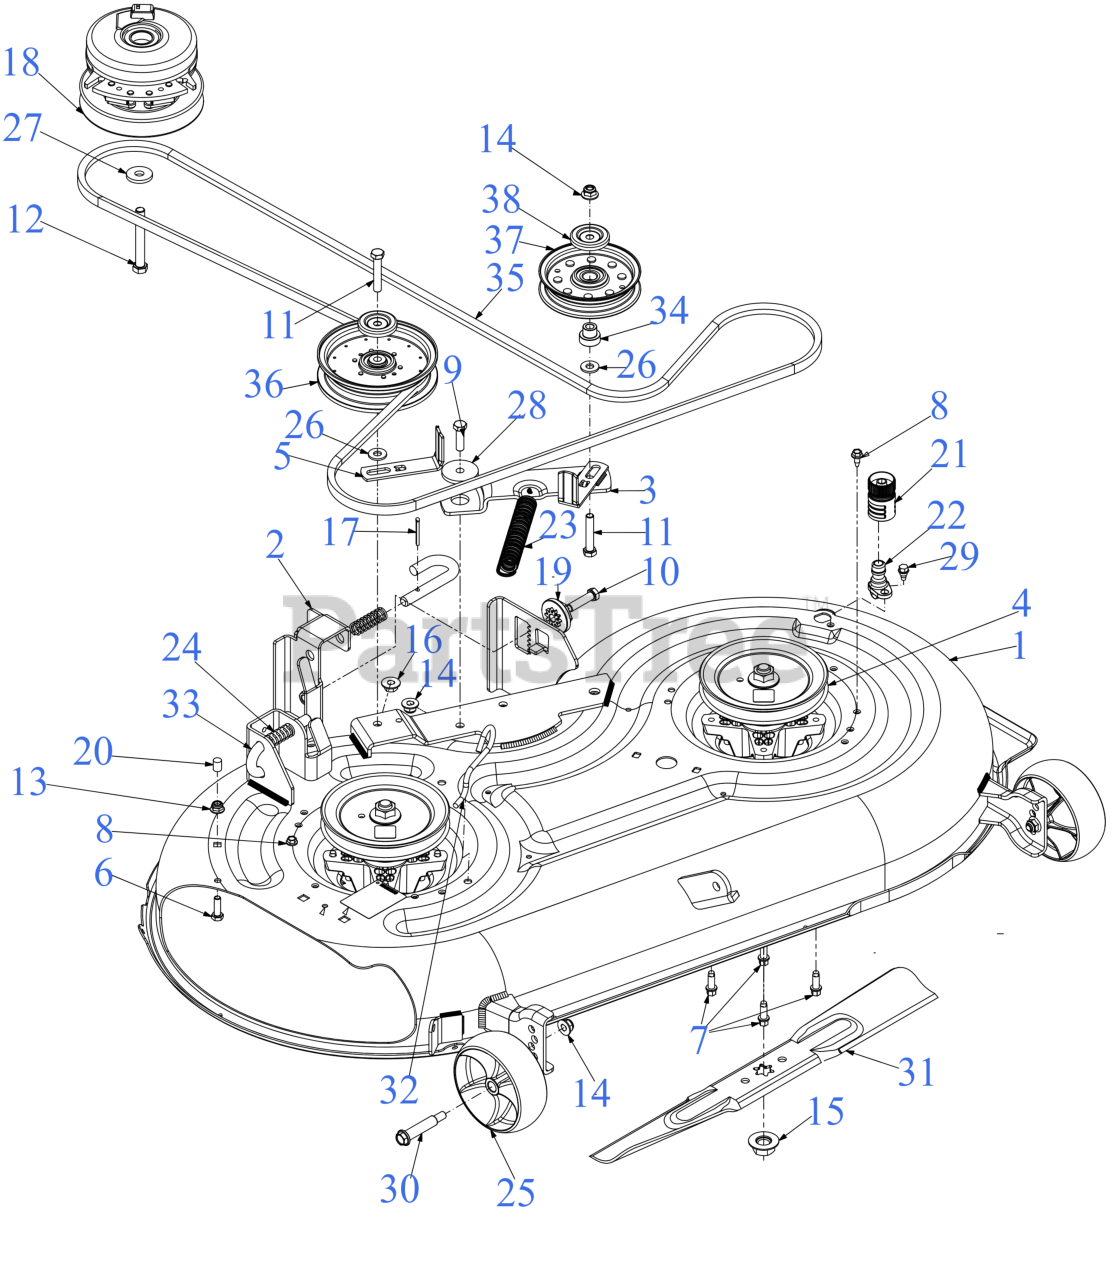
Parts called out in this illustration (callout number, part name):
3	42" IDLER PIVOT BRACKET
4	SPINDLE ASSEMBLY
4	Cub Cadet SPINDLE ASSEMBLY
6	SCREW 5/16-18 x 1.0 GR5
7	SCREW 5/16-18 x .875
8	SCREW 1/4-20X.625
9	SCREW 3/8-16 x 1.25 GR5
10	SCREW 3/8-16X1.5 GR5
11	SCREW 3/8-16 x 2.0 GR5
12	SCREW 7/16-20 x 3.25 GR5
13	FLANGE LOCK NUT 5/16-18
16	FLANGE LOCK NUT
17	COTTER PIN-5/32 DIA
18	ELECTRIC PTO CLUTCH
19	DECK ADJUSTMENT GEAR
21	WATER NOZZLE ADAPTER
22	DECK WASH NOZZLE
23	EXTENSION SPRING .94 x 6.75 RZT
24	COMPRESSION SPRING .66 OD x 1
25	DECK WHEEL (5.0 DIA x 1.875)
26	FLAT WASHER .385X.870X.090
27	FLAT WASHER .445 x 1.248 x .170
28	SHOULDER SPACER
29	SHOULDER SCREW 1/4-20 x .50
30	SHOULDER BOLT (.50 X 2.0 x 3/8 -16)
31	21.23" BLADE (2N1)
31	Cub Cadet 42" BLADE SET
31	Genuine Factory Parts 42" BLADE SET(2N1)
31	Troy-Bilt 42" BLADE SET(2N1)
31	21.23" BLADE (2N1) (XTREME)
31	Cub Cadet BLADE SET (XTREME)
31	BLD:XTREME SET MTD
31	42" 6 PT STAR LOW LIFT/SAND BLADE
31	21.33" BLADE (HI-LIFT)
31	21.23" BLADE (MULCH)
32	DECK SPRING HOOK
33	DECK RELEASE PIN
34	SHOULDER SPACER
35	BELT A SEC x 114.24"
35	Cub Cadet 42"RZT DECK BELT (04317)
35	Genuine Factory Parts 42" DECK DRIVE (954-04137A)
36	FLAT IDLER PULLEY
37	IDLER PULLEY 4.25 DIA
38	IDLER PULLEY CAP
